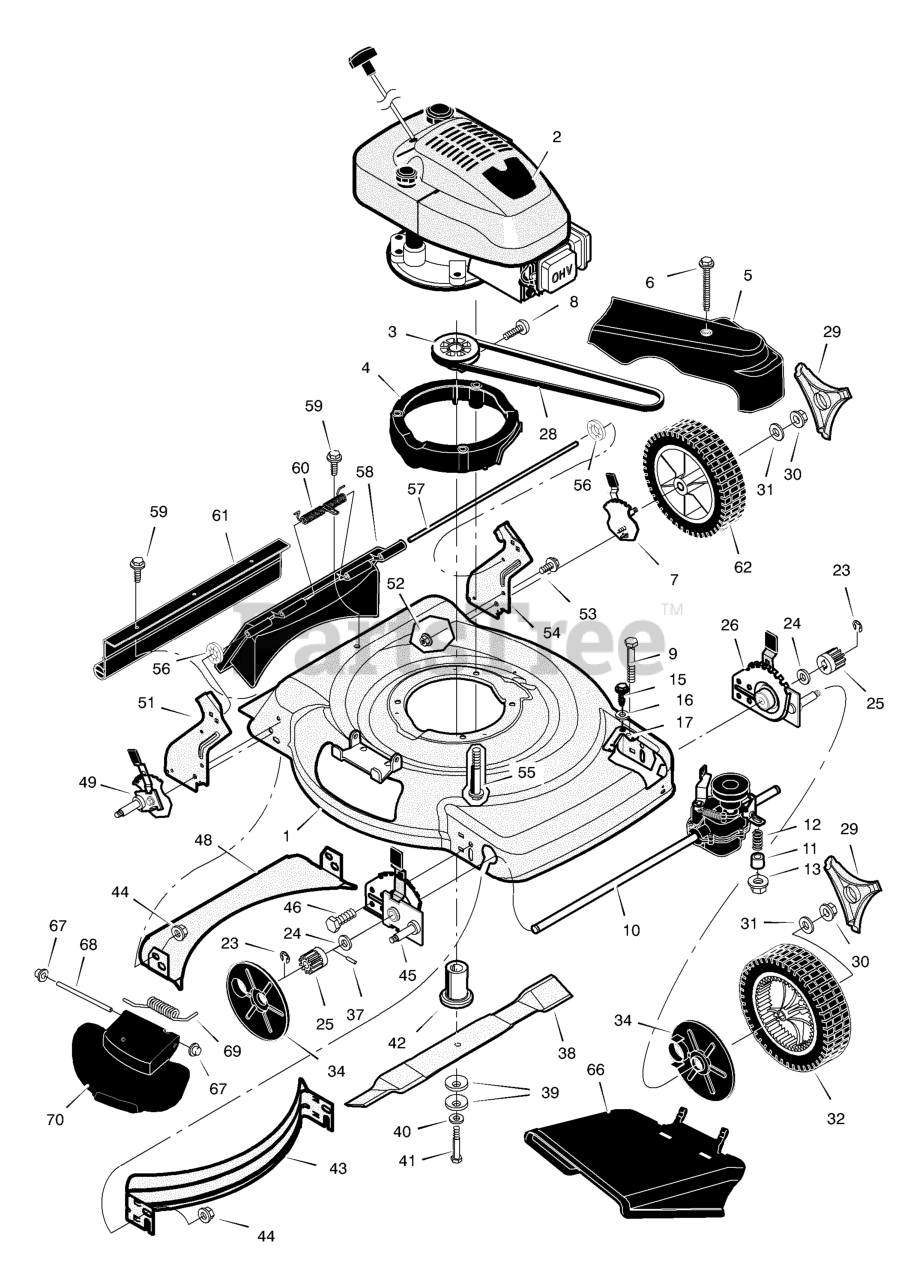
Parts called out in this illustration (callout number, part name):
1	Housing
2	Engine *
3	Pulley, Drive
4	Spacer, Engine
5	Cover, Belt (Black)
7	Adjuster, Left Rear Height
9	Bolt
10	Transmission *
12	Spring, Compression
13	Nut
15	Screw
16	Washer
17	Bracket, Belt Cover
25	Gear, Pinion
26	Adjuster, Left Front Height
29	Cap, Hub
30	Nut, Flange
31	Washer
32	Wheel & Tire, Front
34	Cover, Dust
37	Pin, Drive
39	Washer, Belleville
42	Adapter, Blade
43	Baffle, Front
44	Nut, Flange
45	Adjuster, Right Front Height
46	Bolt
48	Baffle, Rear
49	Adjuster, Right Rear Height
51	Bracket, Right Handle
52	Nut, Flange
53	Bolt
54	Bracket, Left Handle
55	Bolt, Engine
56	Retainer
57	Rod, Pivot
58	Door, Rear (Black)
60	Spring
61	Guard, Rear
62	Wheel & Tire, Rear
66	Deflector, Chute
67	Push On Cap
68	Rod, Pivot
69	Spring, Torsion
70	Cover, Mulch (Black)
